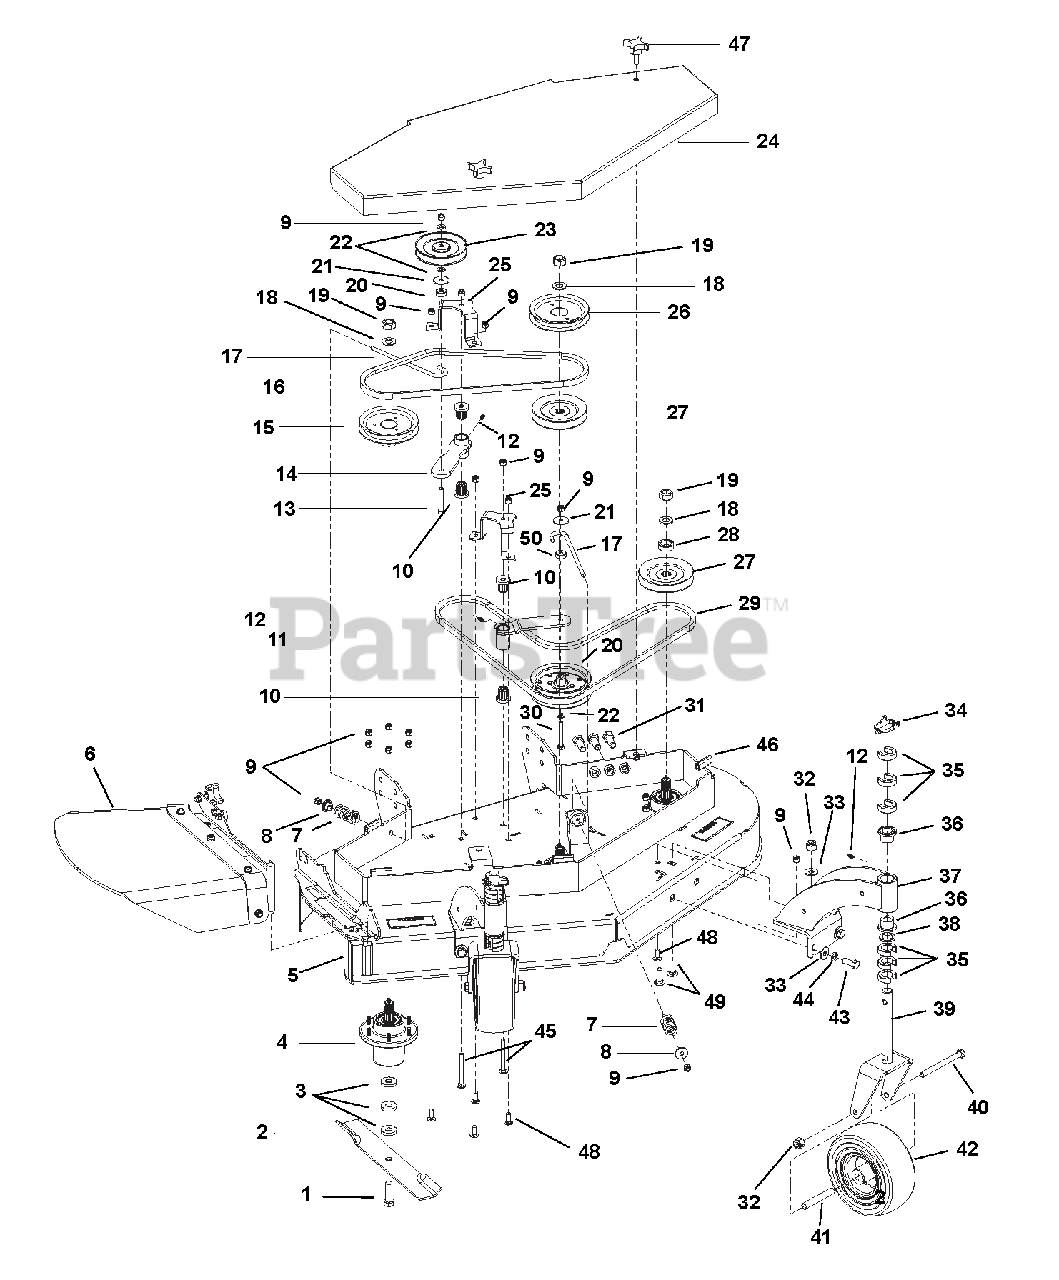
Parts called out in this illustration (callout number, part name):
1	BOLT, 5/8-11 X 2.00 HEX 8 Y
2	BLADE, 16.500 X .80 LIFT
3	WASHER, .630X1.50X.250 FLAT Y
4	ASSY, SPINDLE S/O
5	DECK W/DECALS 48 ARIENS GRWLK
6	ASSY, DISCHARGE SHIELD ARIENS
7	SPRING, COM 1.22X.162X2.50 Y
8	KEEPER, SPRING
9	LOCKNUT, 3/8-16 NYLOC Y
10	BRG, FLG M10XM25XM27 FLUTED
11	WLDT, IDLER ARM WITH OFFSET
12	FTG, 1/4-28 STRGT GREASE ZERK
13	@BLT-HEX .38-16X2.50 GR5 YWZC
14	WLDT, IDLER 36 FXWLK G2
15	PULLEY, SPLINE SPINDLE LSE
16	BELT, HB 51.4 EL AMD
17	J-BOLT, 3/8-16 X 7.88 Y
18	WASHER, .75X1.3125X.120
19	LOCKNUT, 3/4-16 CROWN PL
20	PULLEY, FLAT 5.00X.375 W/BRG
21	WASHER, .375X1.50X.063 FLAT Y
22	WASHER, .406X.813X.065 FLAT Y
23	PULLEY, IDLER 5.0 V-GROOVE
24	WLDT, BELT SHIELD 48 ARIENS
25	BRACKET, IDLER
26	SPLINE, SPINDLE PULLEY OFFSET
27	PULLEY, SPLINE SPINDLE SH
28	SPACER, SPINDLE TOP-PULLEY
29	BELT, HB WRAPPED
30	@BLT-HEX .38-16X2.75 GR5 YWZC
31	BOLT, HEX 5/8-11 1.5" GR8 YWZC
32	LOCKNUT, 1/2-13 NYLOC Y
33	MANUAL, OWNERS RAPID XZ FRENCH
34	PIN, KLIK .438X2.00
35	C-SPACER, 1.00 X 1.77 X .500
36	BRG, FLG 1.00X1.25X1.00
37	WLDT, STRUT FRONT WHEEL ARIENS
38	BUSHING, 1.03 X 1.50 X .179 Y
39	WLDT, CASTER YOKE ARIENS
40	@BLT-HEX .50-13X5.50 GR5YWZC
41	TUBE, CASTER AXLE
42	ASSY, WHEEL AND TIRE 9X3.5
43	@BLT-HEX .50-13X1.25 GR5 YWZC
44	WASHER, .500 MED SPRG LOCK Y
45	BOLT, 3/8-16X3.50 CRG 5 Y
46	TRIM, LOCK 1/4" EDGE
47	KNOB, 3/8 X 1.25 - 4 PRONG
48	@BLT-RDHDSQNK .38-16X1.00 G5YZ
49	@BLT-RDHDSQNK .50-13X1.50 G5YZ
50	BUSHING, .380 X 1.00 X .410 Y
